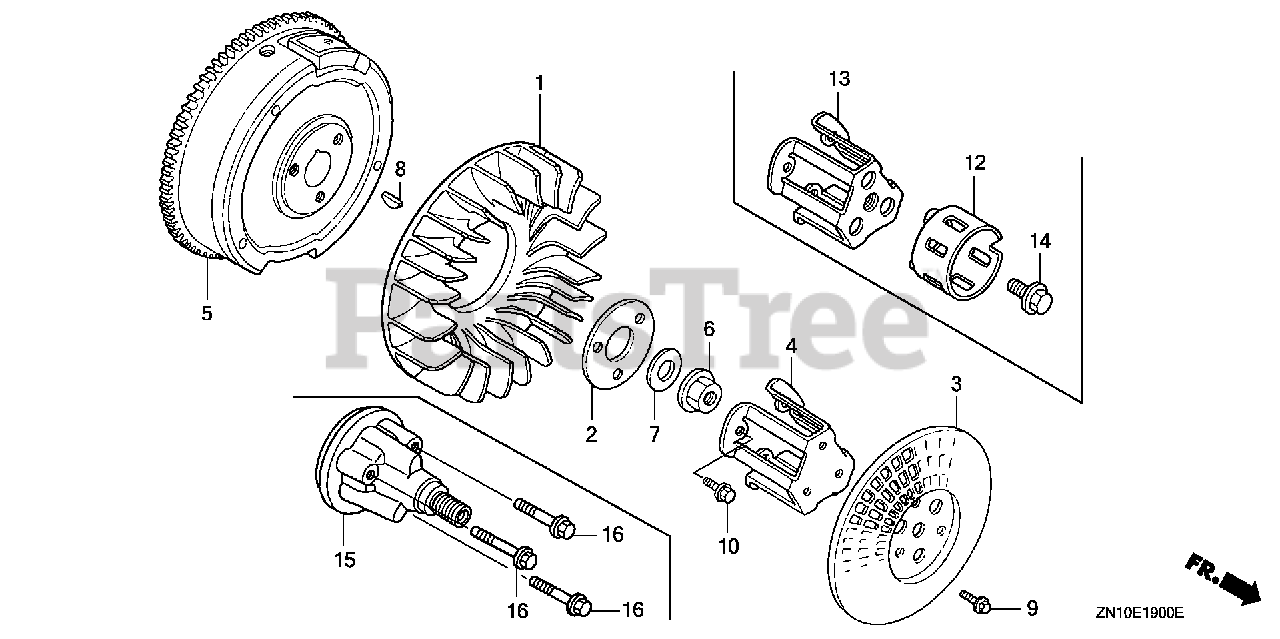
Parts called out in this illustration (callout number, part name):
1	FAN, COOLING
3	GRID, SCREEN
4	HOLDER, SCREEN GRID
6	NUT, FLANGE (20MM)
7	WASHER (20MM)
8	KEY, SPECIAL WOODRUFF (25X18)
9	BOLT, FLANGE (6X12)
10	BOLT, FLANGE (8X16)
